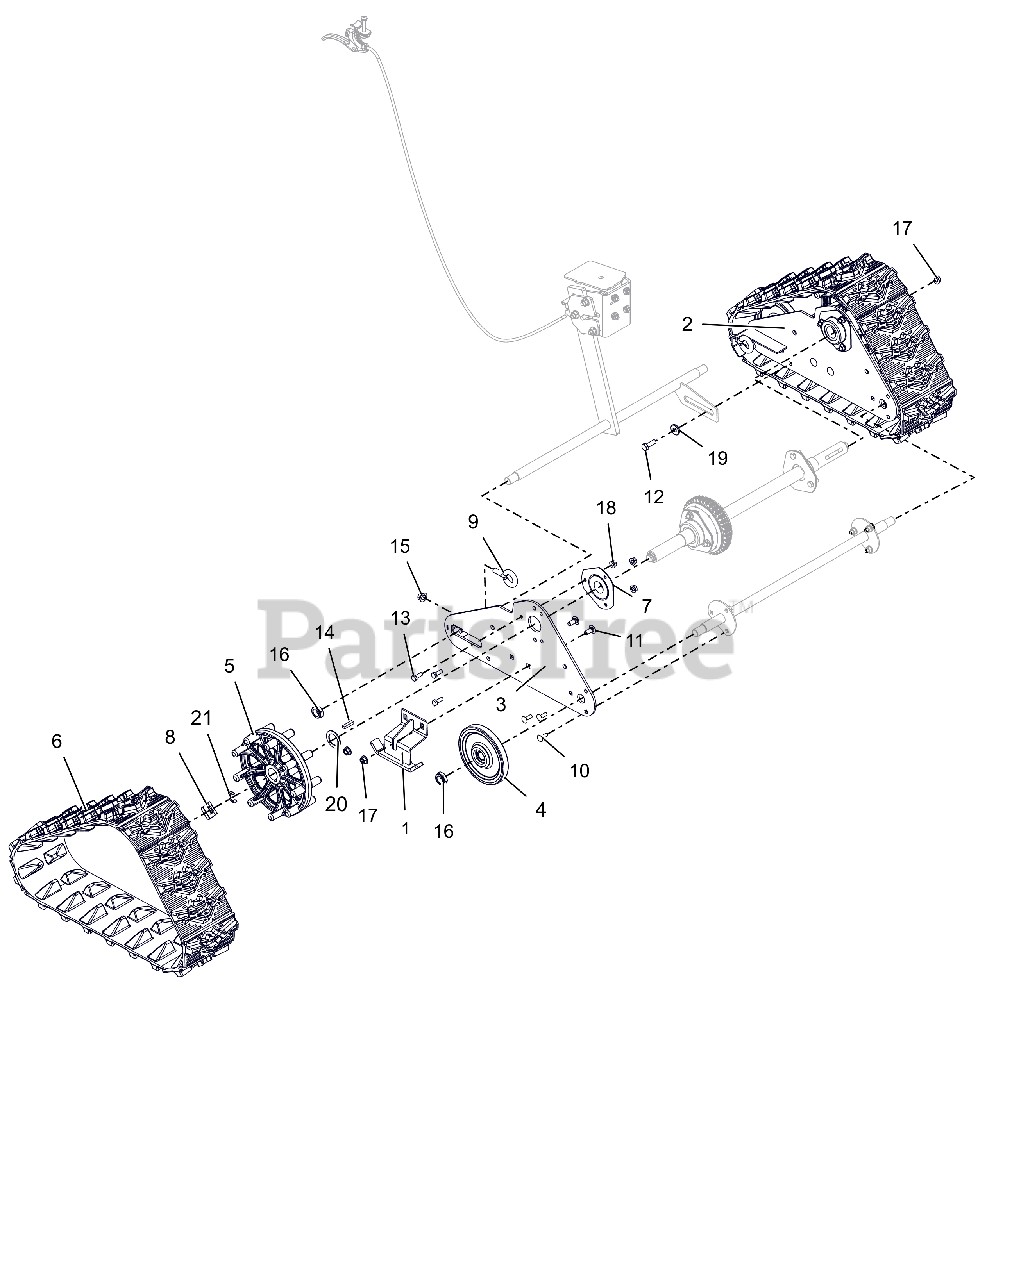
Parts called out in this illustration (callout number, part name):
1	RUNNER, GUIDE-TRACK
2	SIDE PLATE, LH-TRACK
3	SIDE PLATE, RH-TRACK
4	WHEEL, BOGIE - SINGLE BEARING
5	WHEEL, MACHINED DRIVE
6	TRACK, RUBBER
7	BRG-FLG 1.003/1.000 3 BOLT
8	CLIP, SNAP .625 DIA
9	BLT-EYE .375-16X.880 YWZC
10	@BLT-RDHDSQNK .25-20X.75 G5YZ
11	@BLT-RDHDSQNK .31-18X.75 G5YZ
12	@BLT-HEX .31-18X1.00 GR5 YWZC
13	@BLT-HEX .25-20X.75 GR5 YWZC
14	KEY-RECT .25X.188X1.00
15	NUT-LK-CTR-FLG .38-16 YWZC
16	@NUT-LK-NYL .625-18 YWZC
17	@NUT-LK-TOP-FLG .31-18 YWZC
18	@NUT-LK-TOP-FLG .25-20 YWZC
19	BSHG-FLG .325X.499X.3X.875
20	WSHR-FL-STL 1.010X1.505X.062YZ
21	RG-RTNG-EXT .625X.042
